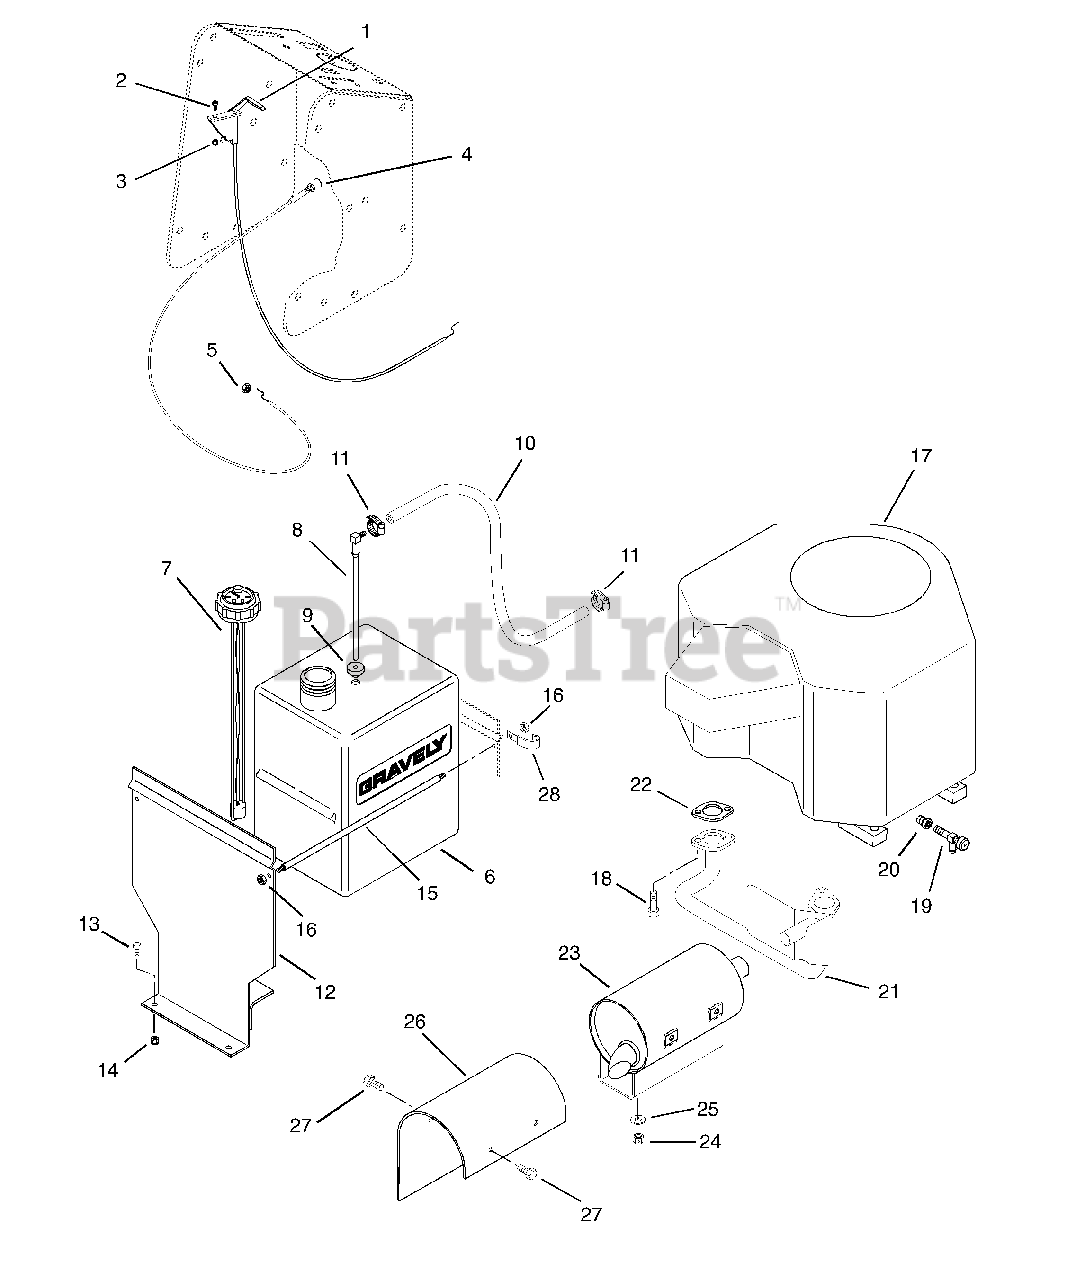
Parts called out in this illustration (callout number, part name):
1	Throttle Cable (015)
1	Throttle Cable (017)
2	Screw-Machine 10-24 x .50
3	Nut-Locking-Nylon 10-24 w/Insert
4	Control-Choke (015)
4	Cable, Choke (017)
5	Nut-Jam .375-24
6	Tank-Fuel
7	Gauge-Fuel
8	Fitting-Tank
9	Bushing
10	Gas Line Hose 1/4" x 52"
11	Hose Clamp
12	Weldment-Tank Bracket
13	Bolt-Hex .31-18 x .75 Grade 5
14	Nut-Locking-Center .31-18 Grade 2
15	Rod-Tank
16	Nut-Locking-Center .25-20
17	Engine-Kohler CV 25 HP (015)
17	Engine-Briggs & Stratton 21 HP (017)
18	Screw-Socket Head M8-1.25 x 20 mm
19	Cock-Oil Drain
20	Adapter-Oil Drain
21	Manifold-Kohler CV18-25 (015)
21	Manifold (017)
22	Gasket-Exhaust
23	Muffler (Includes 090663 Heat Shield)
24	Nut-Locking-Center .38-16
25	Washer-Flat-Steel .438 x 1.00 x .083
26	Heat Shield (Included with 09065600 Muffler)
27	Bolt, Hex M5 - .8 x 8 mm
28	J-Clamp
